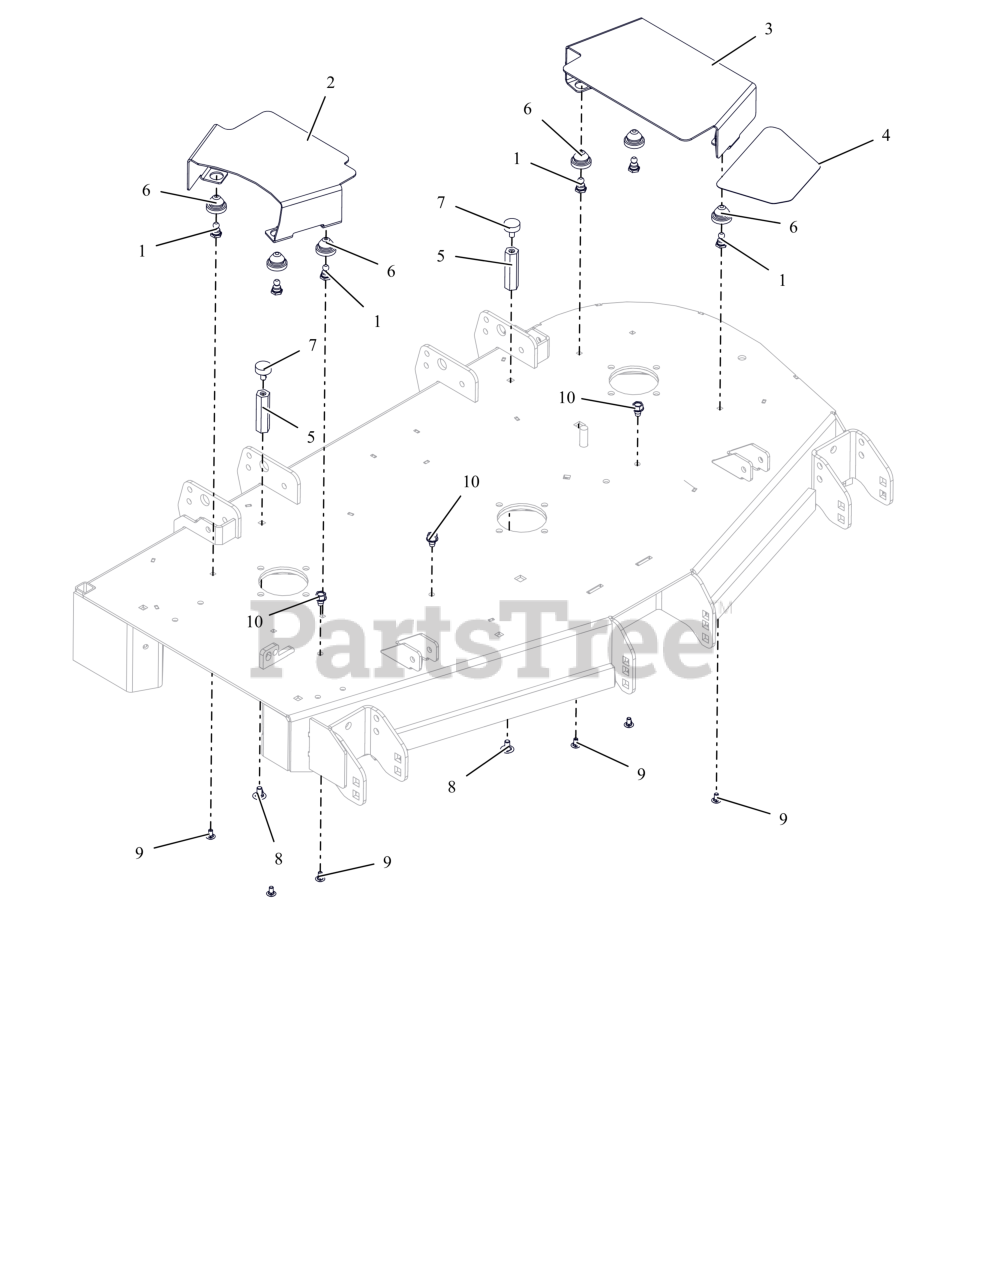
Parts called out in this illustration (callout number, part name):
1	STUD, BALL FEMALE .250-20 THREAD
2	GUARD, RH DECK BELT (RED)
3	GUARD, LH DECK BELT (RED)
4	GRIP, STEP ANTI SKID
5	NUT, COUPLING .31-18 2.75 LG
6	COUPLING, RUBBER PUSH-IN
7	BUMPER, RUBBER
8	BLT, RHSSN .31-18X.625 G5 ZCC
9	BLT, RHSSN.25-20X.500 G5 ZCC
10	SCR,TAP .375-16X.50 HWH TR ZCC
